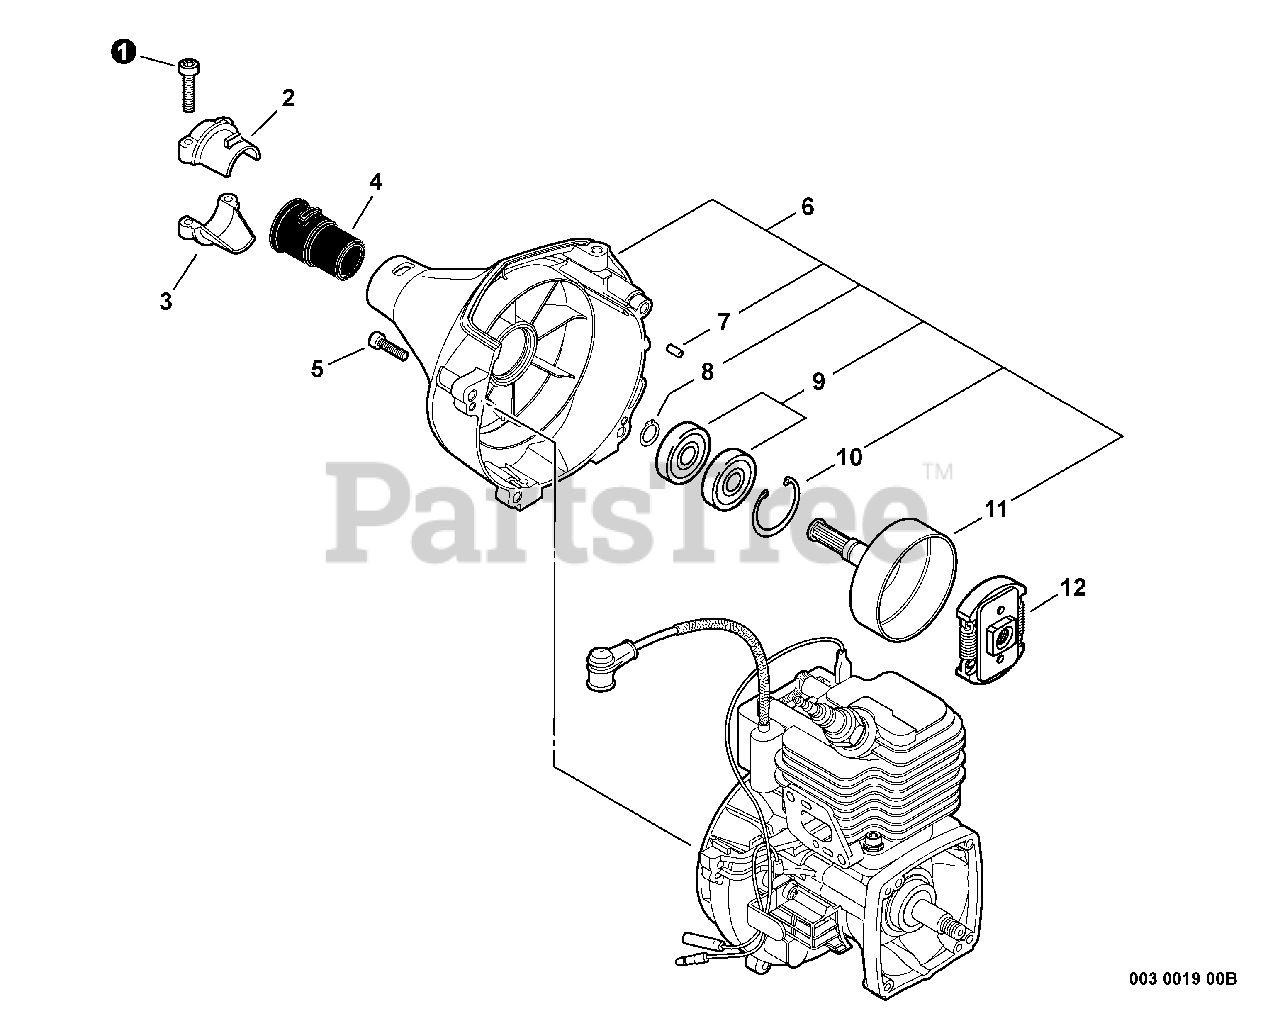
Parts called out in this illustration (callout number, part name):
1	BOLT, TORX 5×20
2	HOLDER, MAIN PIPE - UPPER
3	HOLDER - LOWER
4	CUSHION Ø25
5	BOLT, TORX 4×16
6	COVER ASSY, FAN
7	PIN, LOCATING 4
8	RING, RETAINING - 12
9	BEARING, BALL 6001
10	RING, SNAP 28
11	DRUM, CLUTCH
12	CLUTCH ASSY
